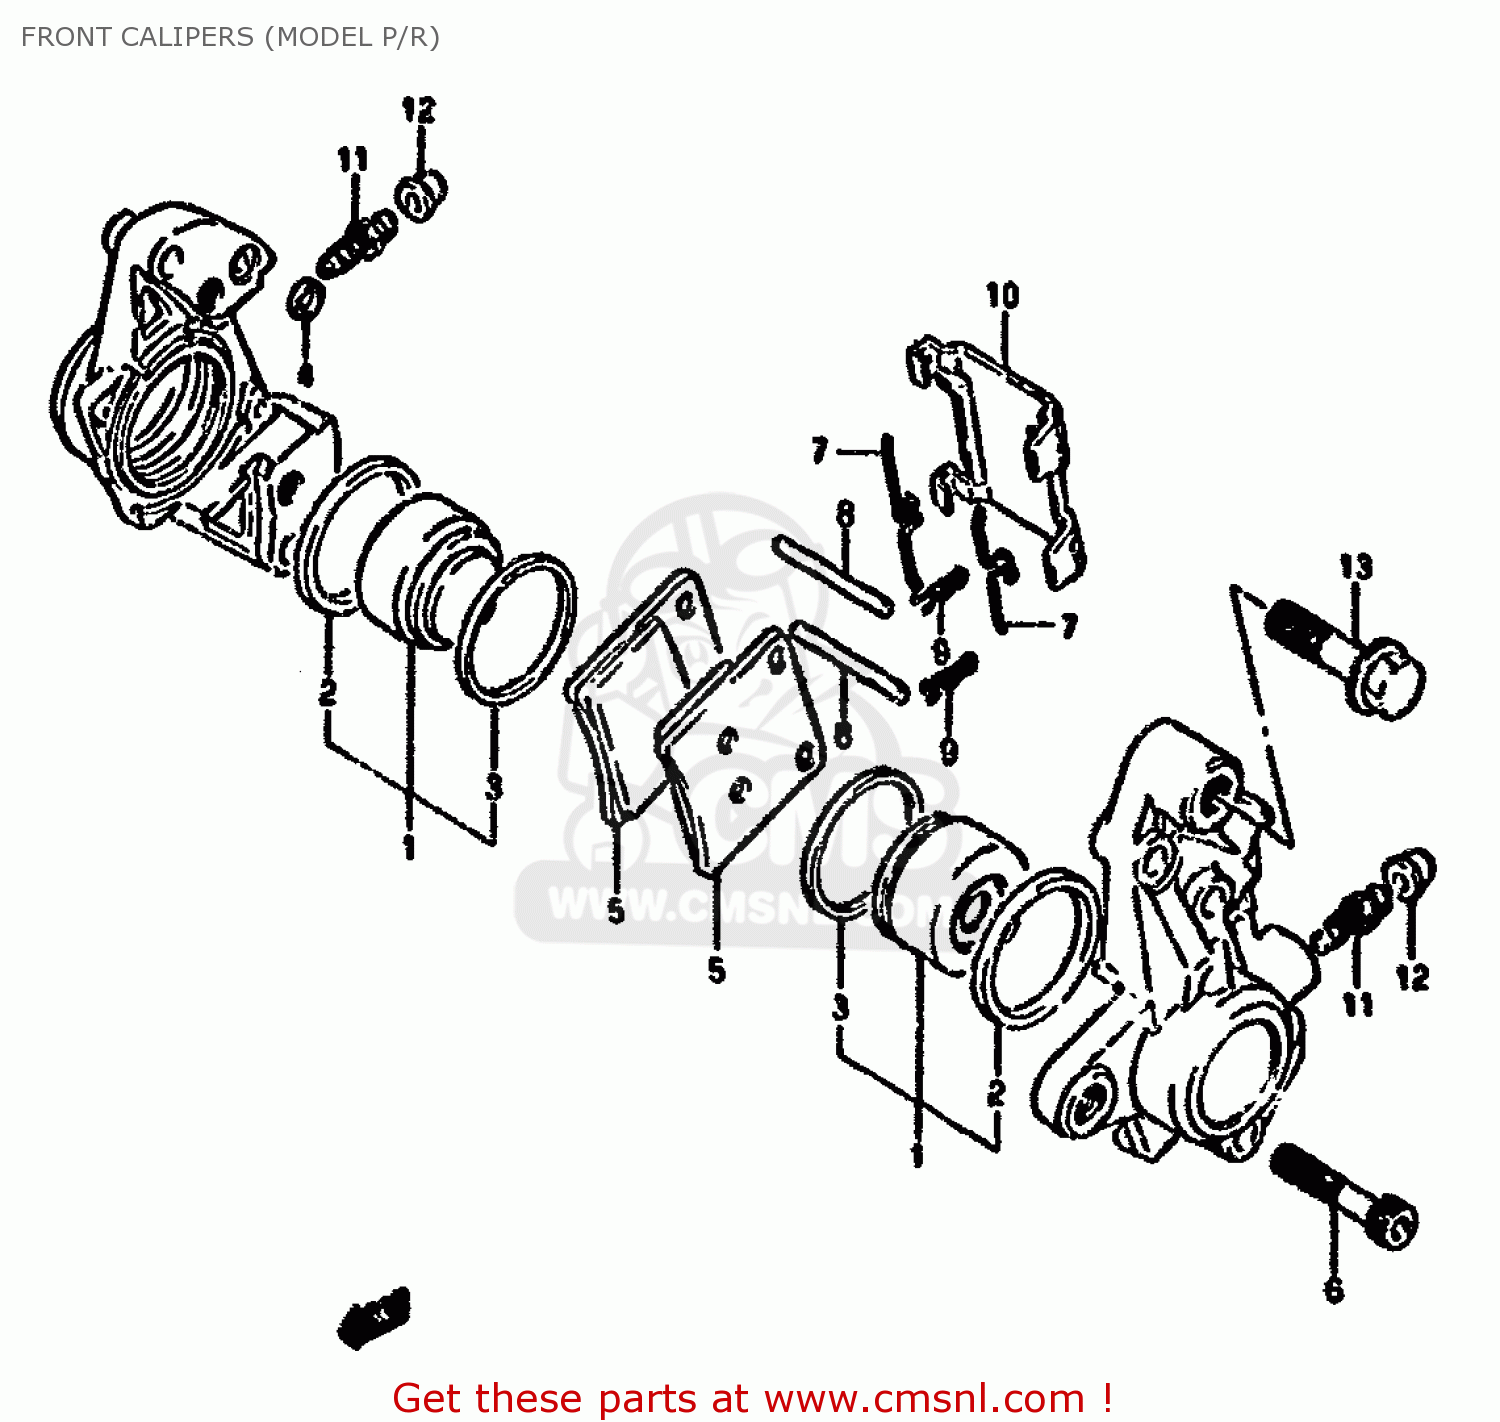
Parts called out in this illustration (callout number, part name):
1	PISTON SET
2	SEAL,PISTON
3	SEAL,WIPER
4	SEAL,JOINT
5	PAD
6	BOLT,CALIPER
7	SPRING
8	PIN,PAD
9	CLIP,PAD PIN
10	COVER,CALIPER
11	BLEEDER
12	CAP,BREATHER
13	BOLT
